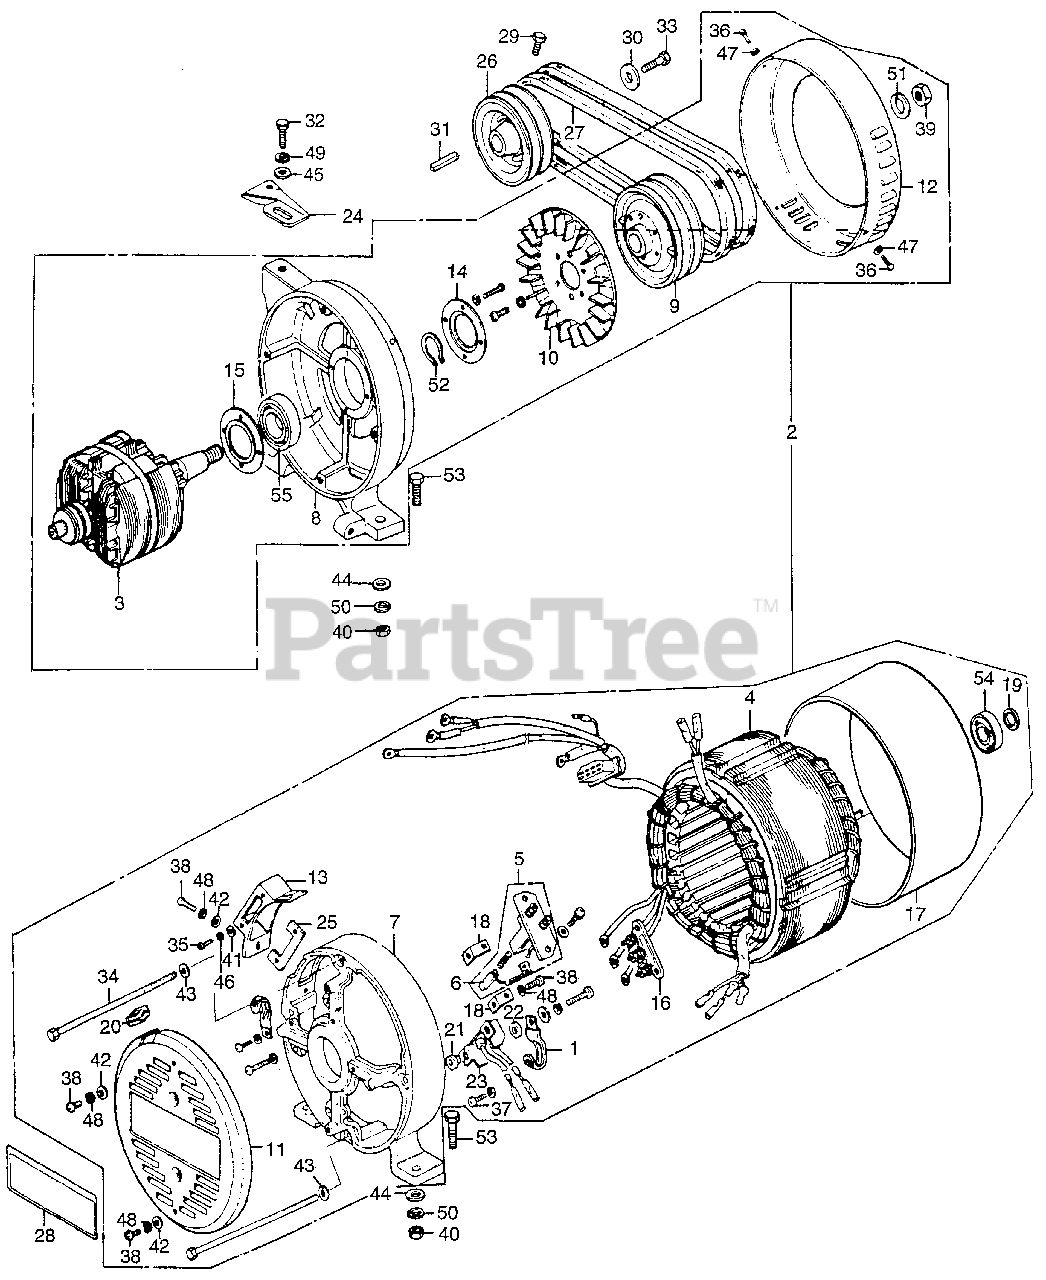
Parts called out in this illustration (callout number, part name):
1	CLAMP B, WIRE
2	ALTERNATOR ASSY.
4	STATOR ASSY.
5	HOLDER, BRUSH
6	BRUSH, CARBON
7	HOUSING, RR. *NH31* (MCKINLEY WHITE) (NOT AVAILABLE)
8	HOUSING, FR. *NH31* (MCKINLEY WHITE)
9	PULLEY *NH31* (MCKINLEY WHITE) (NOT AVAILABLE)
11	COVER, GENERATOR *R8* (BRIGHT RED)
12	COVER, FAN *NH31* (MCKINLEY WHITE)
13	COVER, CONNECTOR *NH31* (MCKINLEY WHITE)
14	COVER A, BEARING (NOT AVAILABLE)
15	COVER B, BEARING
16	TERMINAL, VOLT CHANGE
17	COVER, STATOR *NH31* (MCKINLEY WHITE) (NOT AVAILABLE)
18	STAY, BRUSH HOLDER
19	WASHER, BEARING
20	BUSH, RUBBER
21	BUSH, INSULATING
22	WASHER, INSULATING
23	DIODE ASSY., D.C. (NOT AVAILABLE)
24	STAY, ALTERNATOR (NOT AVAILABLE)
25	PLATE, CONNECTOR SETTING
26	V-PULLEY (60HZ) (NOT AVAILABLE)
27	V-BELT (A-31) (NOT AVAILABLE)
28	PLATE, CAUTION
29	BOLT B, KEY LOCK (7MM) (NOT AVAILABLE)
30	WASHER, LOCK (8MM)
31	KEY (7X7X33)
32	BOLT, HEX. (8X20)
33	BOLT, HEX. (8X25)
34	BOLT, HEX. (6X130) (NOT AVAILABLE)
34	BOLT, HEX. (6X130)
35	SCREW, PAN (3X10)
36	SCREW, PAN (4X6)
37	SCREW, PAN (4X6)
38	SCREW, PAN (5X10)
39	NUT, HEX. (18MM) (NOT AVAILABLE)
40	NUT, HEX. (10MM)
41	WASHER, PLAIN (3MM)
42	WASHER, PLAIN (5MM)
43	WASHER, PLAIN (6MM)
44	WASHER, PLAIN (10MM)
45	WASHER, PLAIN (8MM)
46	WASHER, SPRING (3MM)
47	WASHER, SPRING (4MM)
48	WASHER, SPRING (5MM)
49	WASHER, SPRING (8MM)
50	WASHER, SPRING (8MM)
51	WASHER, SPRING (18MM) (SOURCE: VINTAGE PARTS INC.)
52	CIRCLIP (OUTER) (25MM)
53	BOLT, HEX. (10X32) (SOURCE: VINTAGE PARTS INC.)
54	BEARING, RADIAL BALL (6203UU)
55	BEARING, RADIAL BALL (6205UU)
